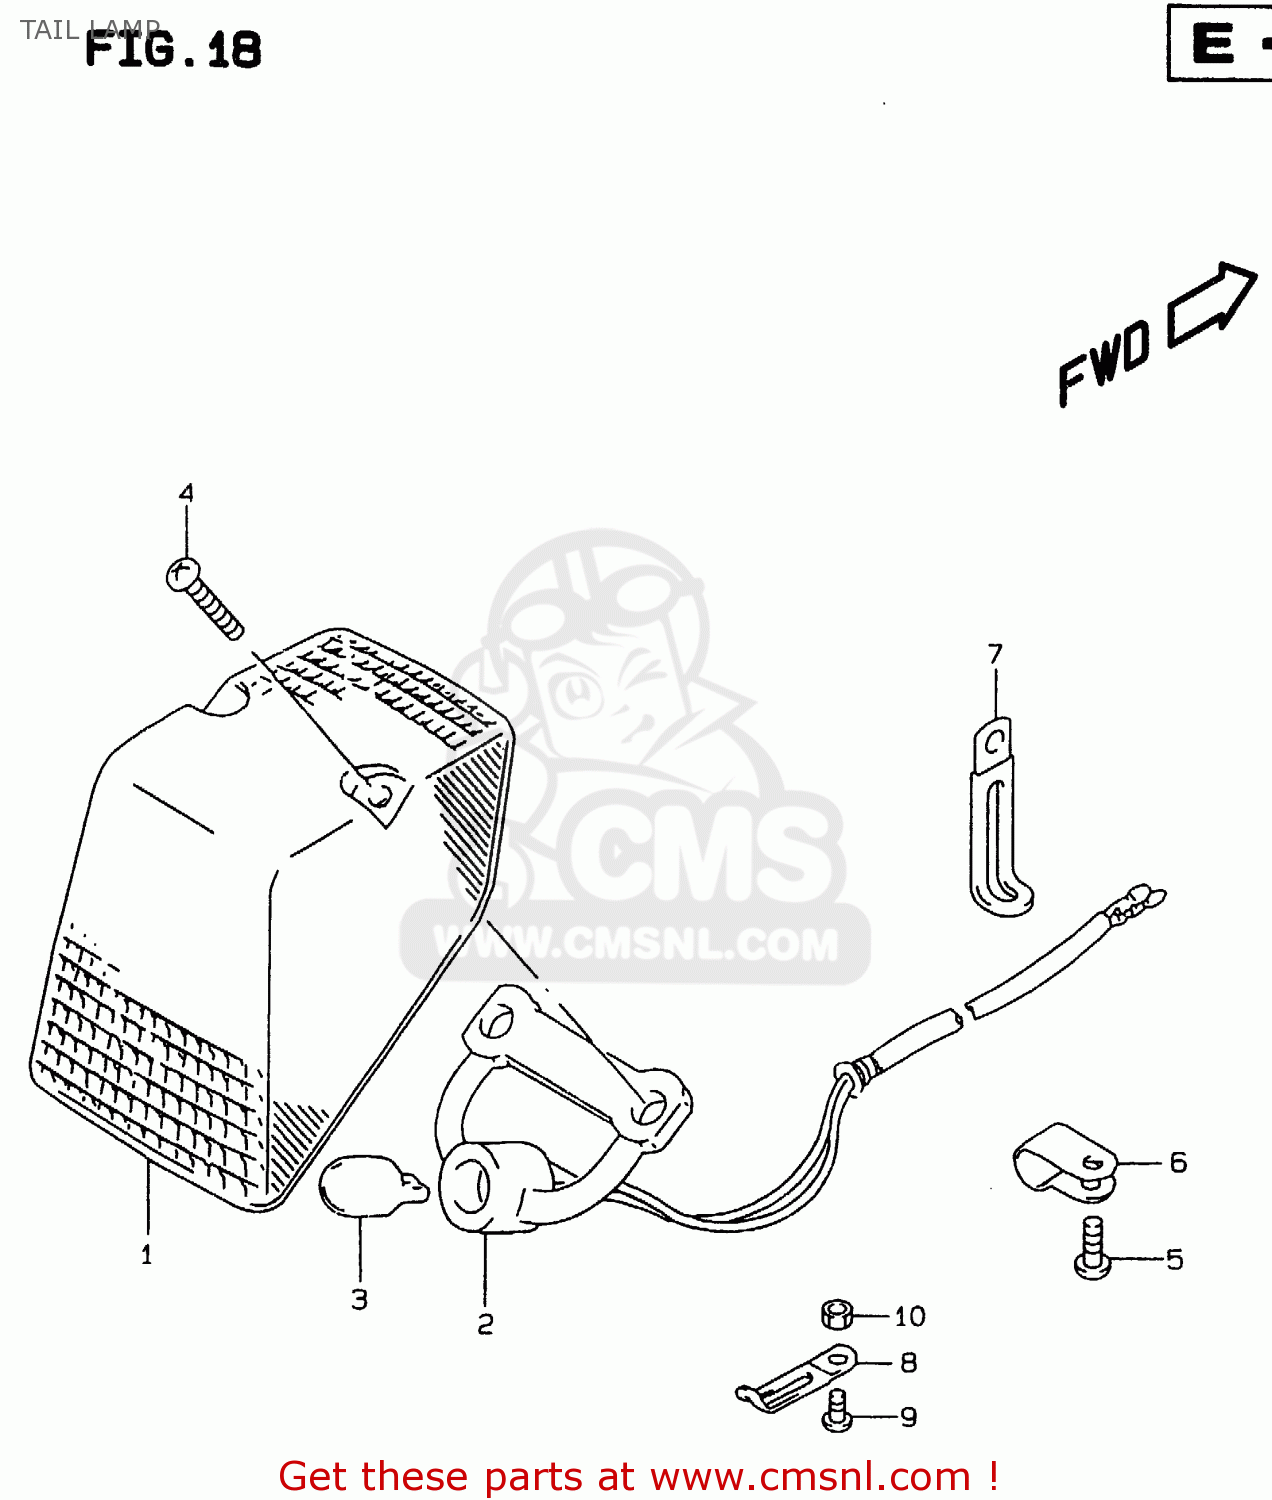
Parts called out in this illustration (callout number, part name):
1	LENS
2	SOCKET & CORD,RR COMBINATION
3	BULB(12V5W)
4	SCREW
5	SCREW, TRUNK BOX
6	CLAMP
7	CLAMP(L:45 T:0.6)
8	CLAMP(L:45)
9	SCREW 6X10
10	NUT 6MM
